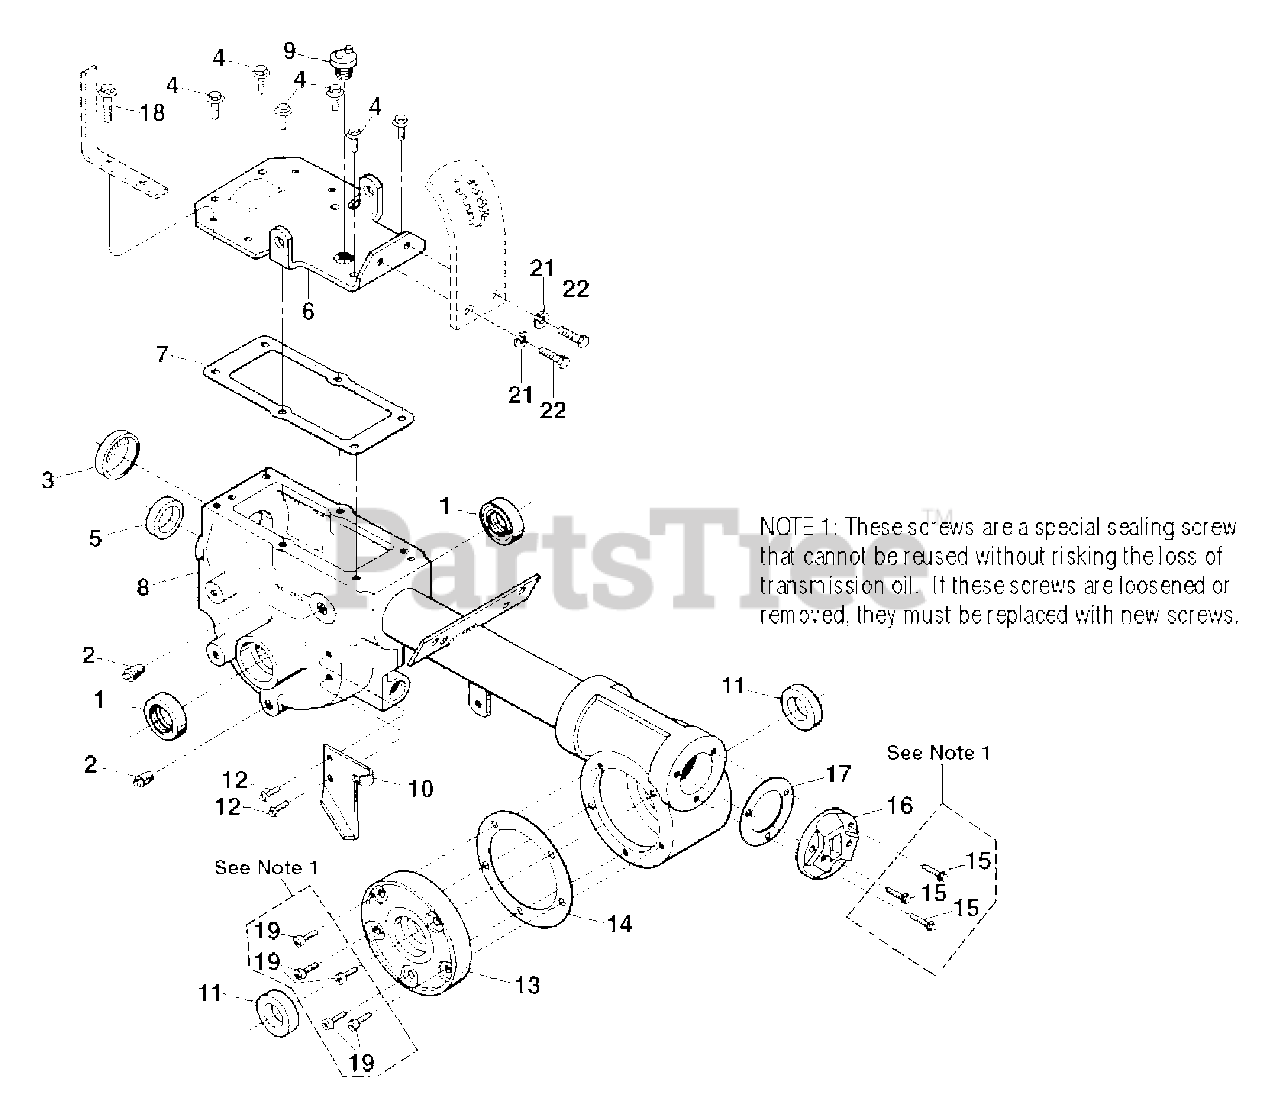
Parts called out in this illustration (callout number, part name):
1	Oil Seal (Double Lip), Wheel Shaft
2	Pipe Plug, 1/4
3	Seal, Transmission Bore
4	Hex Flange Screw, 5/16-18 x 3/4
5	Oil Seal, Input Pinion Shaft
6	Transmission Cover
7	Gasket, Transmission Top Cover
8	Transmission Case Assy. (Inch Tube and Rear Housing)
9	Plug
10	Mounting Plate, Wheel Drive Cable
11	Oil Seal, Tiller Shaft
12	Hex Flange Screw, 5/16-18 x 5/8
13	Tiller Housing Cover, left side 1
14	Gasket, Tiller Housing Cover, .010" (fits all covers)
15	Screw Kit:
16	Rear Bearing Cap
17	Gasket, Rear Bearing Cap, .010" Thick
18	Hex Flange Screw, 5/16-18 x 1"
19	Screw Kit:
21	Lockwasher, 3/8
22	Hex Hd. Screw, 3/8-16 x 3/4
